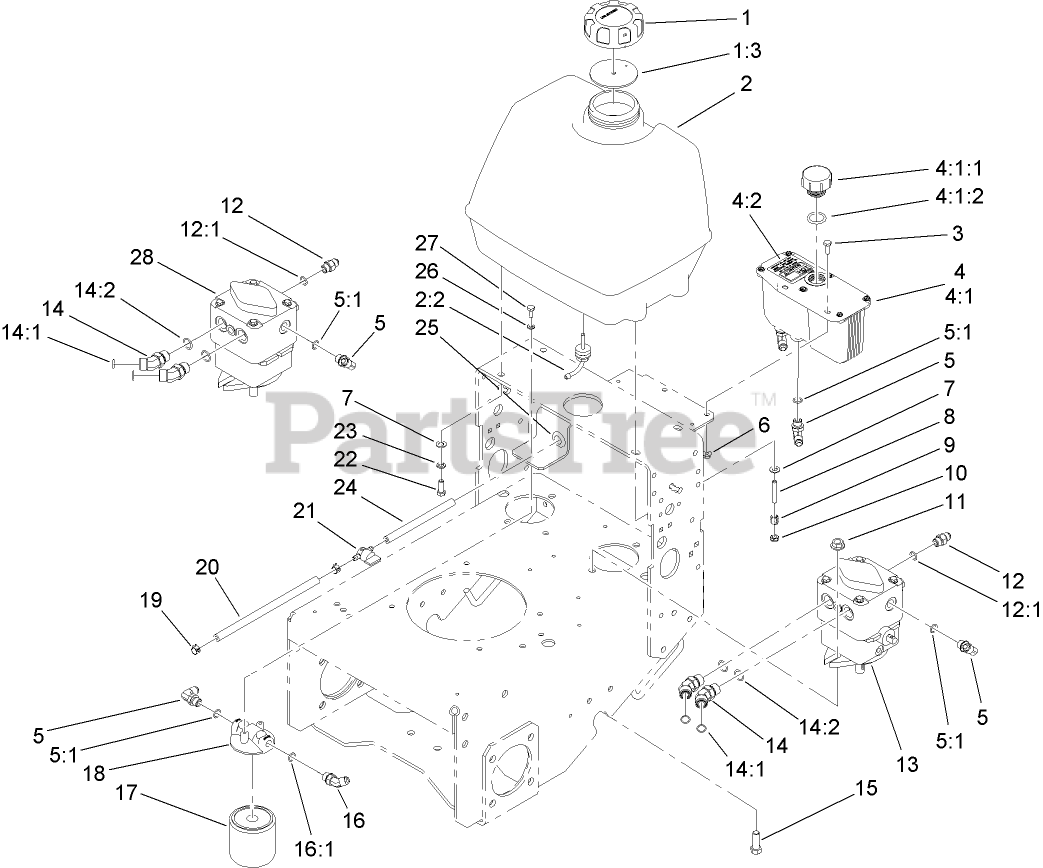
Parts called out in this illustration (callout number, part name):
1	GAS CAP ASM
1:3	GASKET-CAP, GAS
2	FUEL TANK ASM
2:2	FITTING-FUEL, BULKHEAD
3	SCREW-HH
4	HYD Reservoir ASM
4:1	Reservoir-HYD
4:1:1	CAP-RESERVOIR, HYD
4:1:2	GASKET-CAP
4:2	DECAL-TANK, HYD
5	FITTING-ELBOW, 90 DEG
5:1	O-RING
6	NUT-HF
7	WASHER-PLAIN
8	STUD-THREADED
9	SPRING-TANK, FUEL
10	NUT-LOCK, NI
11	NUT-HF
12	FITTING-STRAIGHT
12:1	O-RING
13	PUMP-HYD
14	FITTING-HYD, 45 DEG
14:1	O-RING
14:2	O-RING
15	SCREW-HH
16	FITTING-ELBOW, 45 DEG
16:1	O-RING
17	FILTER-OIL, HYD (WINTER)
17	FILTER-OIL, HYD
18	HEAD-FILTER
19	CLAMP-HOSE
20	HOSE-FUEL
21	VALVE-FUEL
22	SCREW-HH
23	WASHER-LOCK
24	HOSE-FUEL
25	GROMMET
26	WASHER-LOCK
27	SCREW-HH
28	PUMP-HYD
